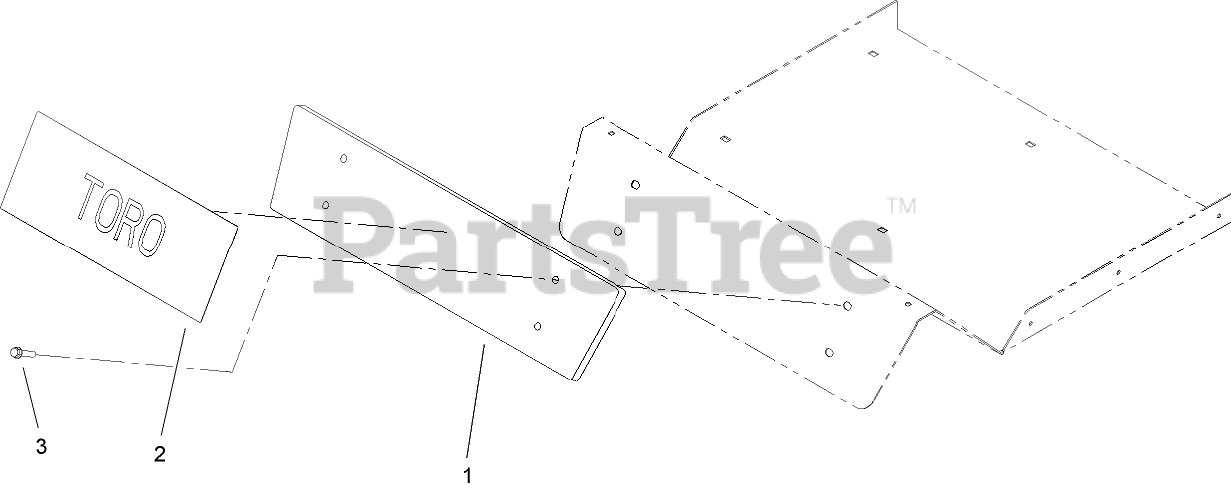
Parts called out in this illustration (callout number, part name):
1	WEIGHT-BAGGER
2	DECAL
3	SCREW-HHF
